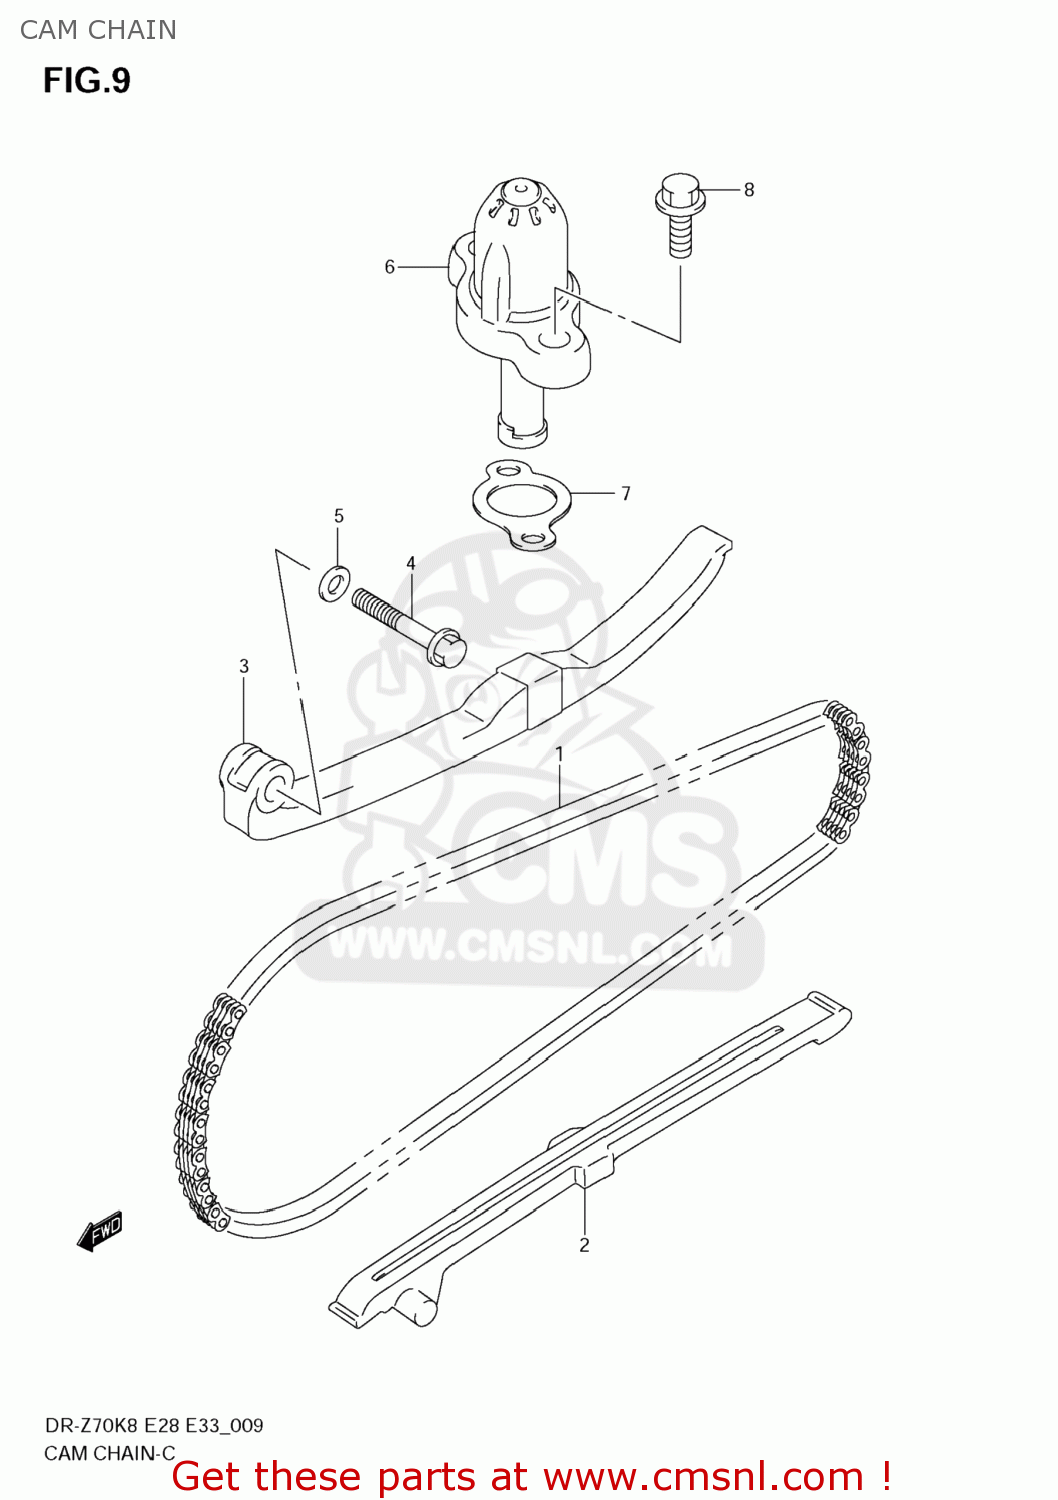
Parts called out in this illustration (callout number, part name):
1	CHAIN,CAMSHAFT DRIVE
2	GUIDE,CAM CHAIN
3	TENSIONER,CAM CHAIN
4	BOLT(6X30)
5	GASKET(6.2X11X1).2 (NAS)
6	VERSTELLER
7	GASKET,TENSIONER ADJUSTER (NAS)
8	BOLT
